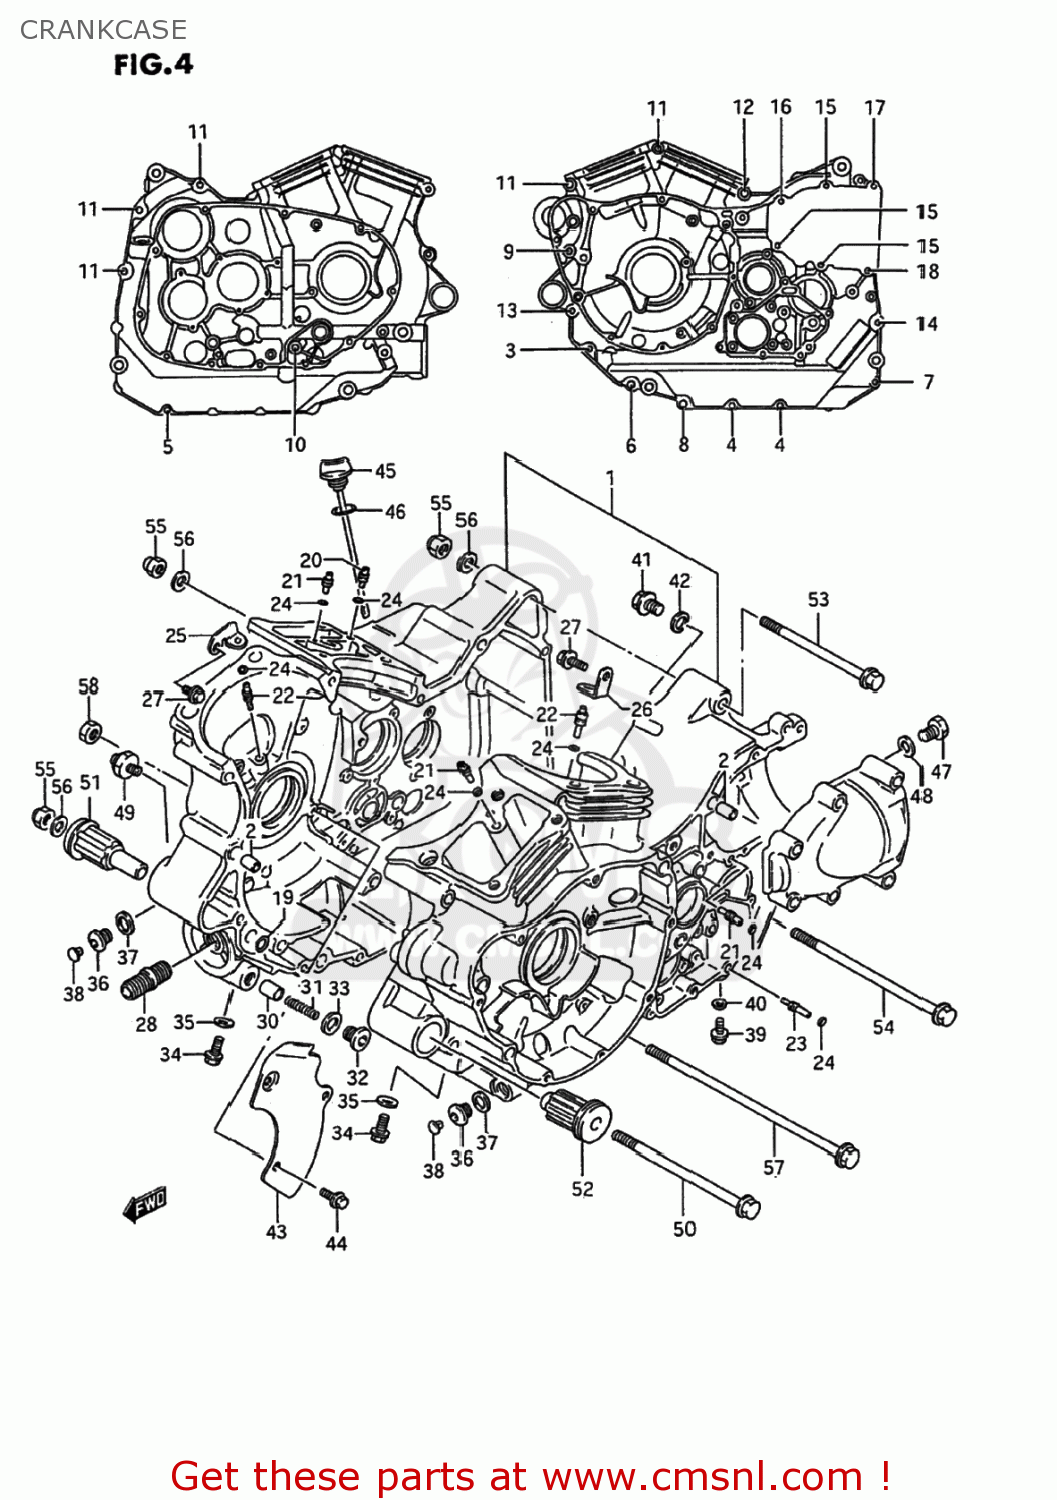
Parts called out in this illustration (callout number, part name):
1	CRANKCASE SET
2	PIN (11X20)(SUS)
3	BOLT
4	BOLT
5	BOLT
6	BOLT
7	BOLT
8	BOLT
9	BOLT
10	BOLT(8X115)
11	BOLT(8X95)
12	BOLT(8X50)
13	BOLT(8X70)
14	BOLT(8X80)
15	BOLT
16	BOLT
17	BOLT
18	BOLT
19	O RING(D:1.9,ID:12.6)
20	JET(2.2)
21	JET,AIR(14)
22	JET,PISTON COOLING(0.8)
23	JET,MISSION OIL(1.4)
24	O RING(D:1.2,ID:4)
25	PLATE,PISTON JET FR
26	PLATE,PISTON JET RR
27	BOLT
28	UNION,OIL STAND
29	PLATE,CRANK THRUST
30	PLUNGER,OIL CONTROLL
31	SPRING
32	PLUG
33	GASKET(16X22X2) (NAS)
34	BOLT
35	GASKET(8.2X14X1).6 (NAS)
36	PLUG,14X12
37	GASKET(14X19.2X2) (NAS)
38	CAP(OD:12)
39	BOLT
40	GASKET(5.8X13X1.2) (NAS)
41	PLUG(12X10)
42	GASKET(12.1X16.2X3.7) (NAS)
43	PLATE,OIL SEPARATOR
44	BOLT
45	GAUGE,OIL LEVEL
46	O RING(D:3.1,ID:16.8)
47	BOLT
48	GASKET(12.1X16.2X3.7) (NAS)
49	SWITCH ASSEMBLY
50	BOLT(10X155)
51	BUSH,ENGINE MOUNTING,R
52	BUSH,ENGINE MOUNTING
53	BOLT(10X135)
54	BOLT(10X180)
55	NUT
56	WASHER
57	BOLT(10X225)
58	NUT
